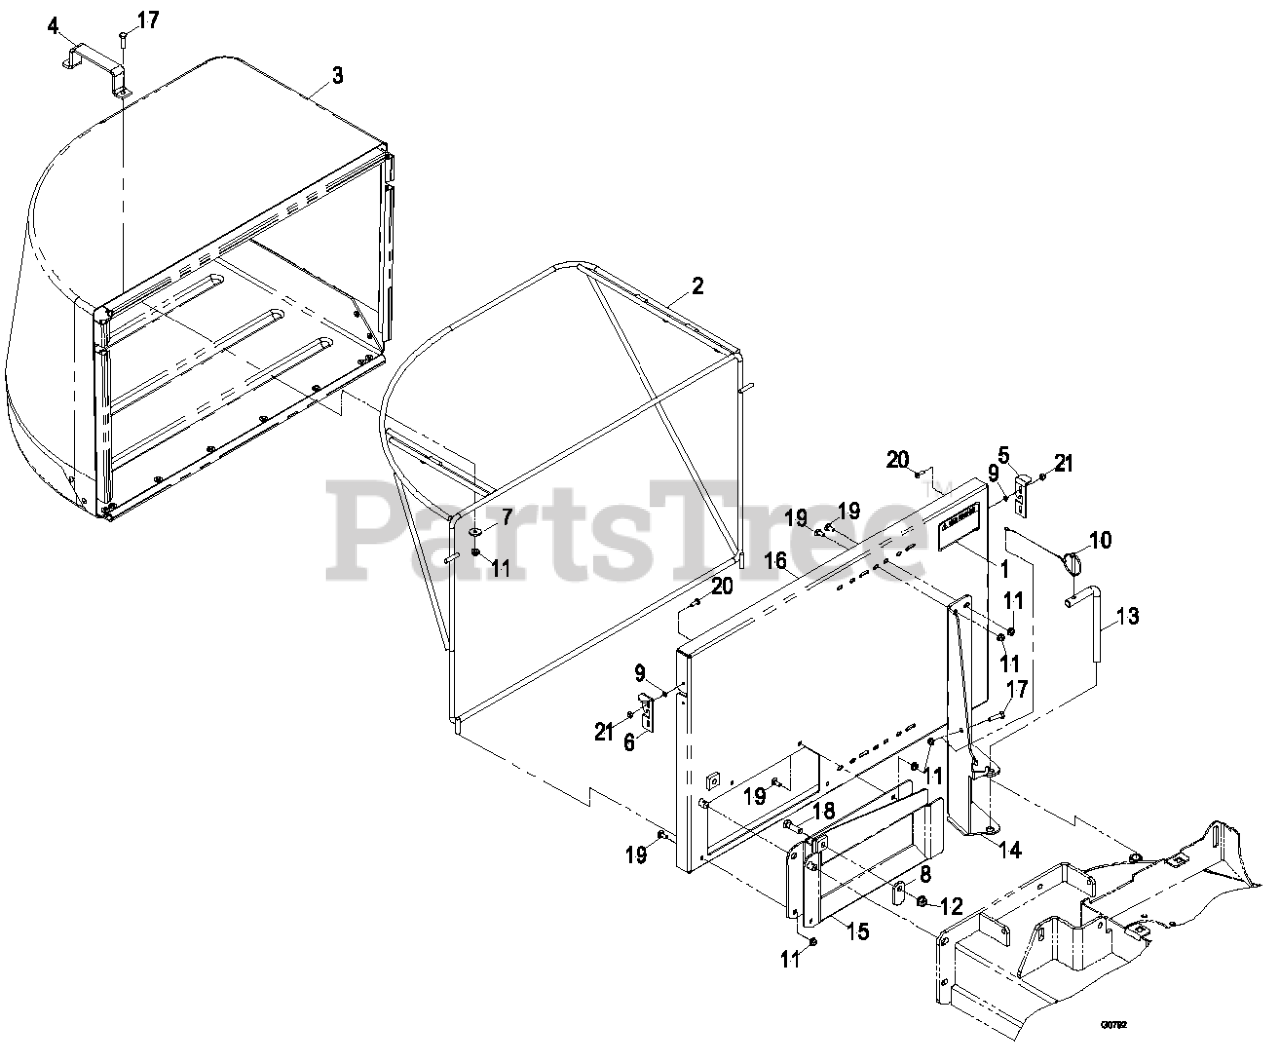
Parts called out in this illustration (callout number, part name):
1	DECAL-WARNING, DISCHARGE
2	FRAME-CATCHER
5	LATCH-CATCHER, LH
6	LATCH-CATCHER, RH
8	LATCH-CATCHER, GRASS
9	WASHER-SPRING
10	PIN ASM-LYNCH
12	NUT-HF, NI
13	PIN,SUPPORT
15	WELD,ADAPTER
16	ASM,BACKING PLT W/DECAL
17	SCREW-HH
18	SCREW-HH
19	SCREW-CARR
20	SCREW-PPH
21	NUT-LOCK, NI
